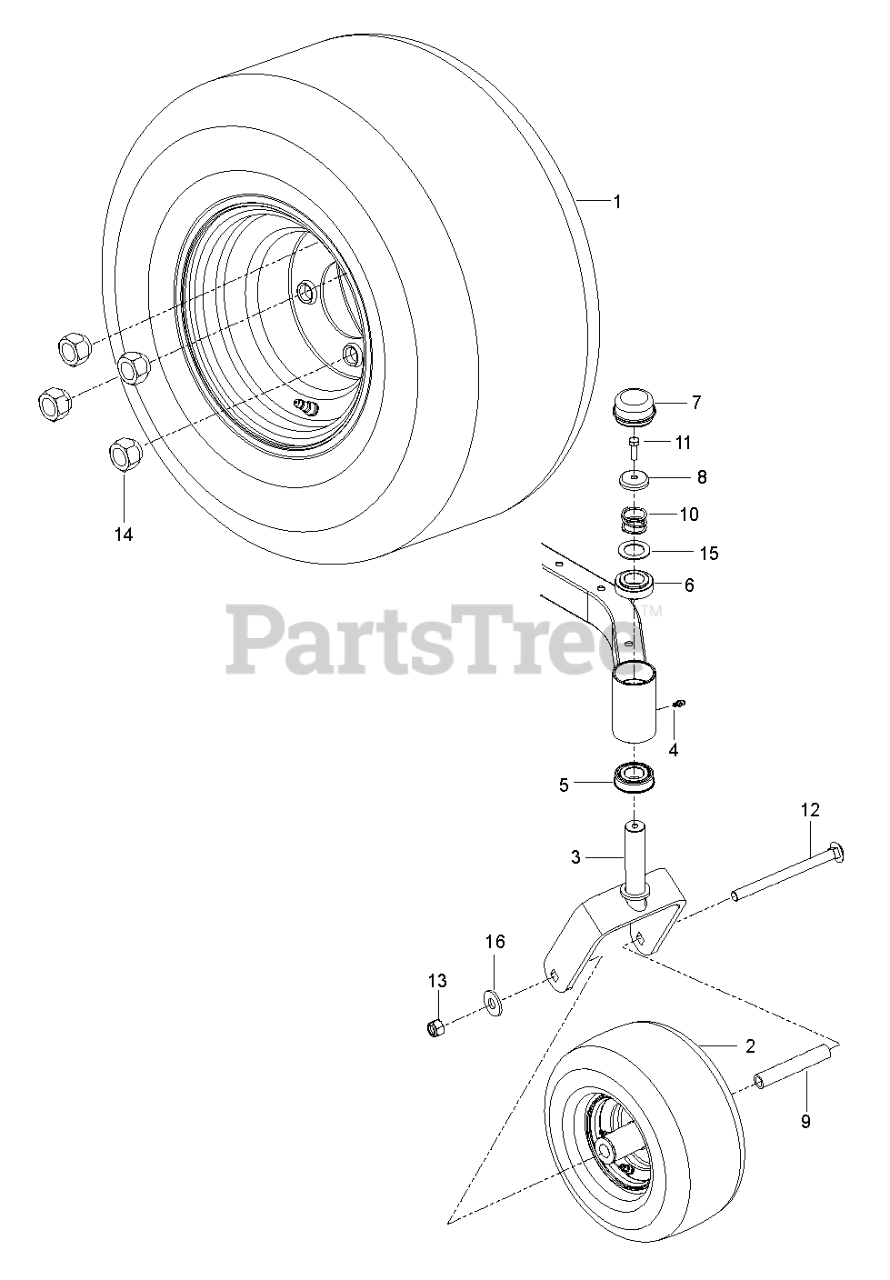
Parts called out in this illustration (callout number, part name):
1	WHEEL.18X8.50-8.4P.K500.8X7.4H
2	WHEEL.ASSY.FRONT.CASTER.11X6-5
3	YOKE CASTER ASM SNAPPER RED X6
4	ZERK, 3/16, DRIVE IN
5	BEARING FLANGED
6	BUSHING, CASTER
7	GREASE CAP
8	CASTER.PLUG
9	SPACER.PIVOT
10	SPRING, CASTER
11	5/16-18X1 HHB G5W/NY
12	RHSNB 1/2-13 X 7.5
13	NUT. 1/2-13 HEX CNTRLK GR 5 ZD
14	NUT.1/2-20.UNF-2B.GR.8.YL
15	WASHER, 1.025 ID X 1.64
16	WASHER.9/16 X 1 3/8 X 12 GA.
